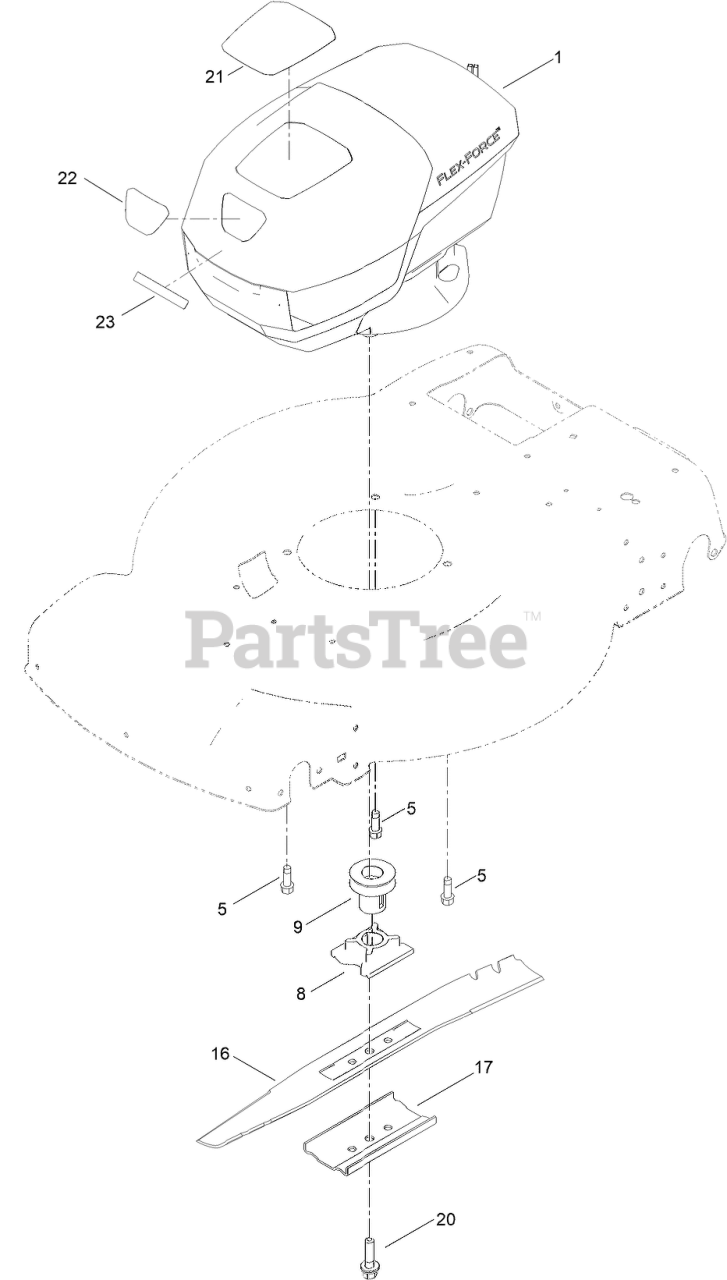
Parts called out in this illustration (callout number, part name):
1	MOTOR MODULE (60V)
5	SCREW-THD FORM, HWH
8	RETAINER-BLADE
9	PULLEY
16	BLADE [BLACK]
17	SUPPORT-BLADE
20	BOLT-BLADE
